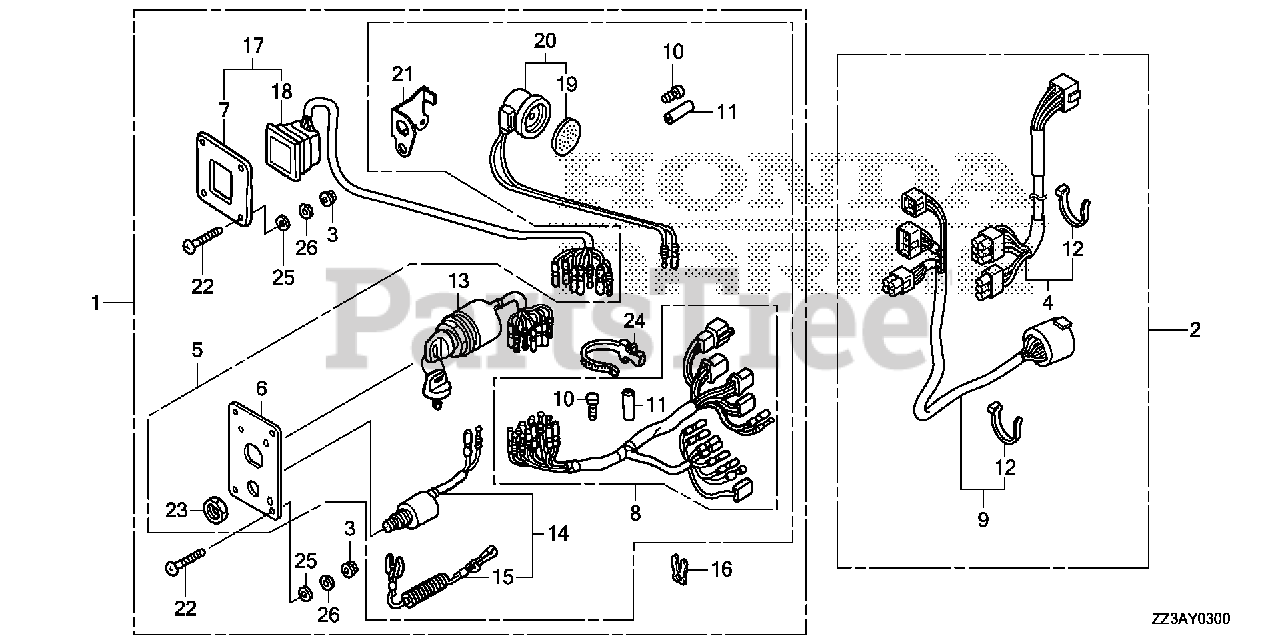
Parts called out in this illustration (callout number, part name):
1	PANEL KIT, SWITCH (4-LED) (B)
2	CABLE SET, PANEL INDICATOR (20FT)
2	CABLE SET, PANEL INDICATOR (25FT)
2	CABLE SET, PANEL INDICATOR (30FT)
3	NUT, FLANGE (5MM)
4	WIRE ASSY., INDICATOR (20FT)
4	WIRE ASSY., INDICATOR (25FT)
4	WIRE ASSY., INDICATOR (30FT)
5	PANEL ASSY., SWITCH
6	PANEL, CONTROL
7	PANEL, CONTROL
8	HARNESS ASSY., SWITCH PANEL
9	CABLE ASSY., SWITCH PANEL (25FT) (NHK MEC)
9	CABLE ASSY., SWITCH PANEL (20FT)
9	CABLE ASSY., SWITCH PANEL (25FT)
9	CABLE ASSY., SWITCH PANEL (30FT)
10	PLUG, CONNECTOR (INNER)
11	PLUG, CONNECTOR (OUTER)
12	TIE, CABLE (2.4X92) (NATURAL)
13	SWITCH ASSY., COMBINATION
14	SWITCH ASSY., EMERGENCY STOP
15	WIRE, EMERGENCY
16	CLIP, EMERGENCY LOCK
17	PANEL ASSY., INDICATOR (4-LED)
18	LAMP ASSY., INDICATION (4-LED)
19	PLATE, TURN SIGNAL BUZZER
20	BUZZER, WARNING
21	BRACKET, BUZZER
22	SCREW, PAN (5X40)
23	NUT, HEX. (16MM)
24	BAND, WIRE HARNESS (150MM) (NATURAL)
25	WASHER, PLAIN (5MM)
26	WASHER, SPRING (5MM)
